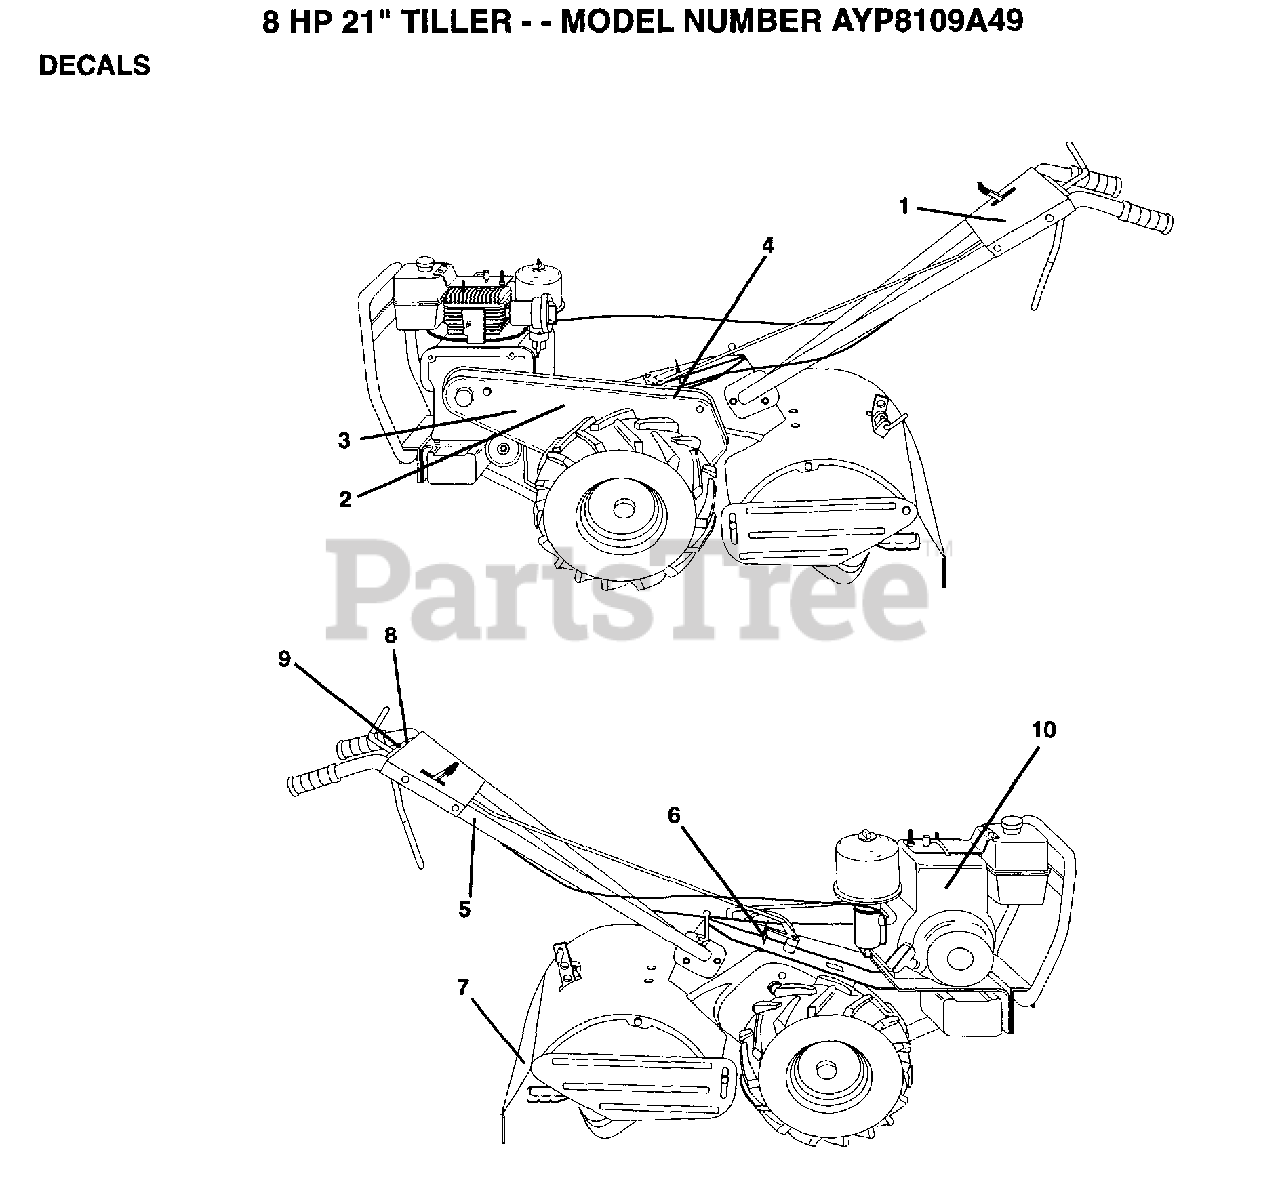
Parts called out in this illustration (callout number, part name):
1	DECAL LOGO CTRL
3	DECAL LOGO GUARD
5	DECAL TI
6	DECAL.SHIFT.IND.
7	DECAL TI
10	DECAL, BRIGGS & STRATTON
